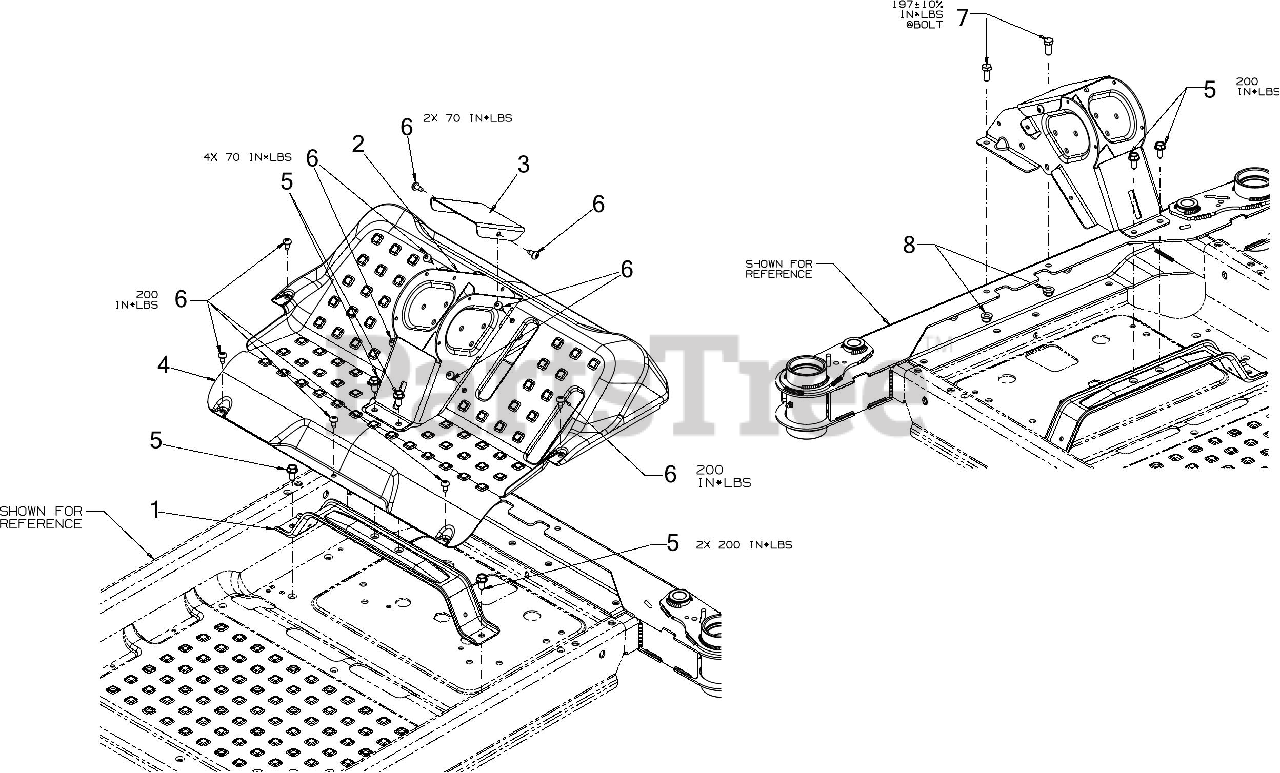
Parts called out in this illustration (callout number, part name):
1	STEERING SUPPORT BRACKET
2	LOWER STEERING COLUMN
3	LOWER STEERING COLUMN
4	FLOORBOARD
5	SCREW 5/16-18 x .750
6	SCREW 1/4-20 x .5
7	SCREW 5/16-18 x .75 GR5
8	FLANGE LOCK NUT 5/16-18
